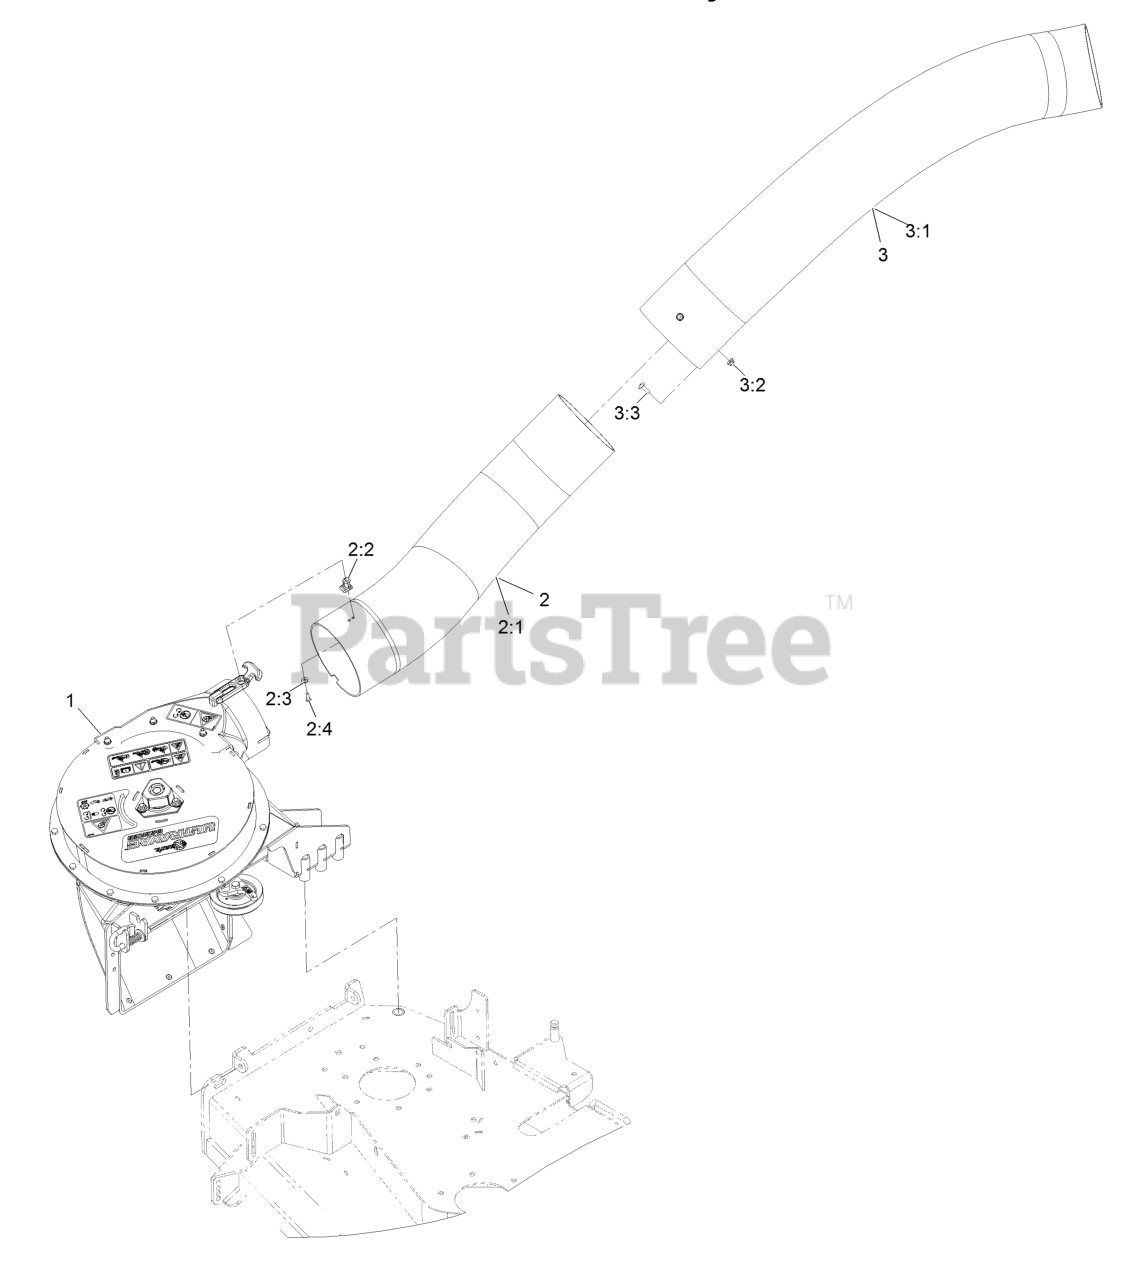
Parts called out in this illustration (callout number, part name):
1	ASM-Blower Uv
2	Lower Tube ASM
2:1	Tube-Lower
2:2	Latch-Keeper
2:3	Washer-#10 Std
2:4	Screw-PPH #10-24 X 5/8
3	Upper Tube ASM
3:1	Tube-Upper
3:2	Nut-Nyloc 1/4-20 Flg
3:3	Screw-PPH 1/4-20 X 3/4
